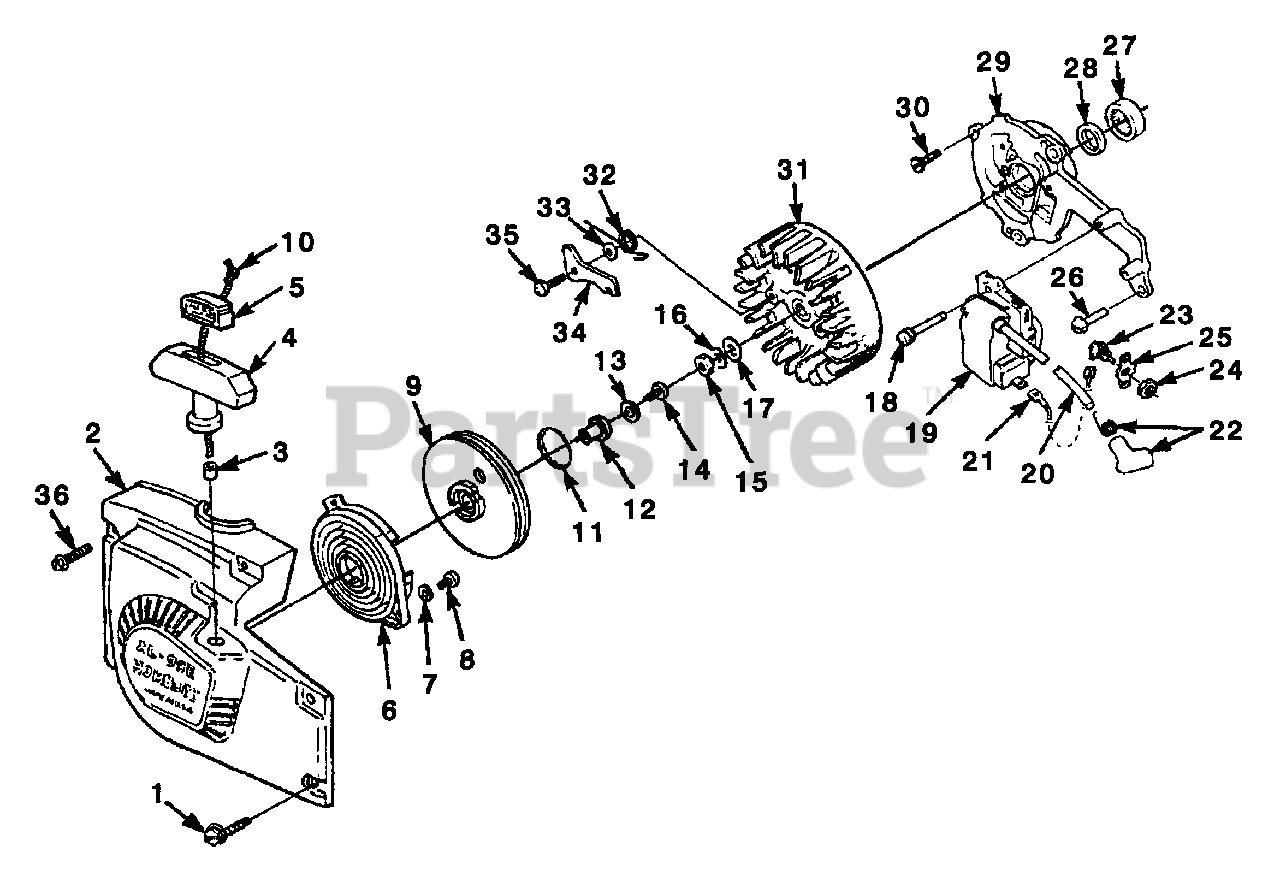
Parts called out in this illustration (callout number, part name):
1	SCREW - Th Hd. (10-24 X 3/4") Torx (T25)
2	HOUSING - Starter w/bushing
3	BUSHING
4	GRIP - Starter
6	SPRING & RETAINER
7	WASHER - Flat
8	SCREW - Thd. Form. (6-32 X 3/8")
9	PULLEY & CUP
10	STARTER ROPE
11	SPRING - Grip
12	BUSHING - Starter Rope
13	WASHER - Flat
14	SCREW - (10 7/8")
15	NUT - Hex (3/8-24)
16	WASHER - Lock (3/8")
17	WASHER - Flat (3/8")
18	SCREW - Sems Hex hd (8-32 X 1")
19	MODULE - Ignition
20	LEAD - High Tension
21	LEAD - Ground
22	TERMINAL - Spark Plug
23	SWITCH - Grounding
24	NUT
25	PLATE - Indicating
26	SCREW - Sems Hex Hd (1/4-20 X 3/4")
27	BEARING - Roller
29	PLATE - Back
30	SCREW - (1/4-20 X 5/8")
32	SPRING - Starter Pawl
33	WASHER - Flat
34	STARTER PAWL
35	SCREW - Shoulder
36	SCREW - Th Hd (10-24 X 1 625) Torx (T25)
